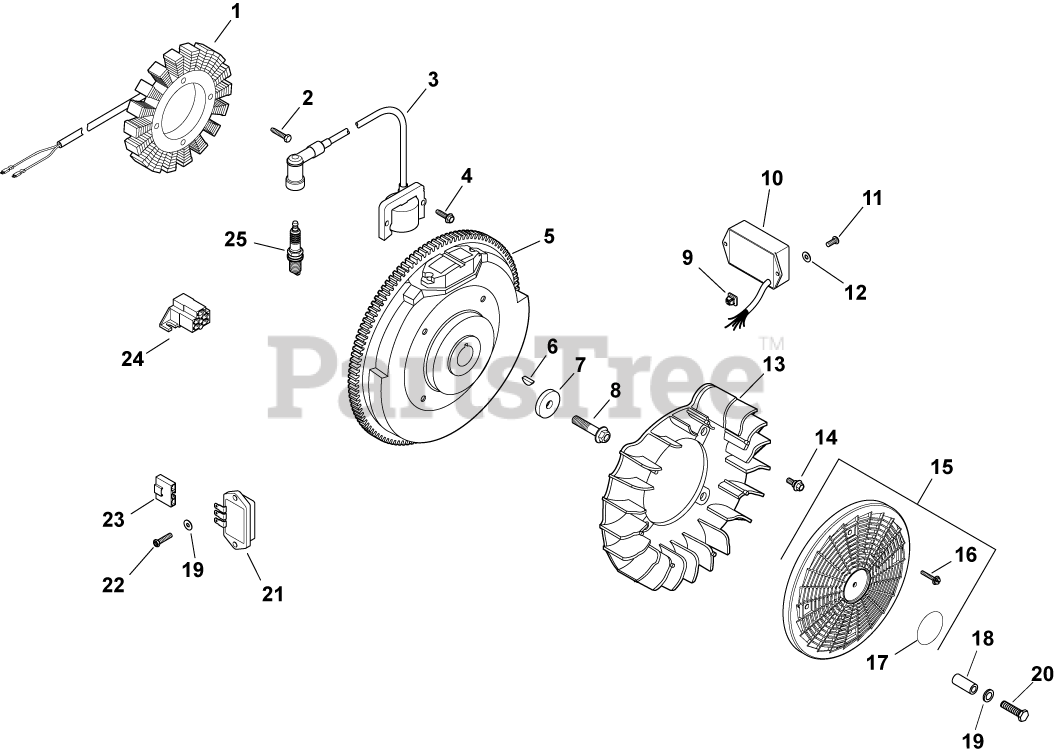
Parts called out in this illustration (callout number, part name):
1	KIT, 25 AMP STATOR ASSY.
2	SCREW, THD FROM M5X0.8X30
3	MODULE, IGNITION
4	SCREW, SKT THD FRM M5X0.8X25
5	FLYWHEEL, PAINTED-USE 24 025 57-S
6	KEY, 3/16" X 5/8"
7	WASHER, FLAT 13/32"
8	SCREW, FLG M10X1.5X45 - (#25086361S)
9	NUT, PLASTIC
10	MODULE, SPEED ADVANCE-DISCONTINUED SEE PB265
11	SCREW, PHL HD #11-16X1/2"
12	WASHER, FLAT 1/4" (O.D. 1/2")
13	FAN USE 24 157 11-S
14	BOLT, SHOULDER
15	KIT, GRASS SCREEN
16	SCREW, FLG SEMS M4X.7X25
17	DECAL, GRASS SCREEN USE 24 113 499-S
18	SPACER - DISCONTINUED
19	WASHER, FLAT 3/16"
20	SCREW, SLT HD CAP M4X0.7X25
21	REG/RECTIFIER (20/25 AMP)-USE 25 403 20-
22	SCREW, PHL HD #11-16X7/8"
23	CONNECTOR, BODY (KM)-USE 25 155 41-S
24	CONNECTOR
25	PLUG, SPARK (STD)
